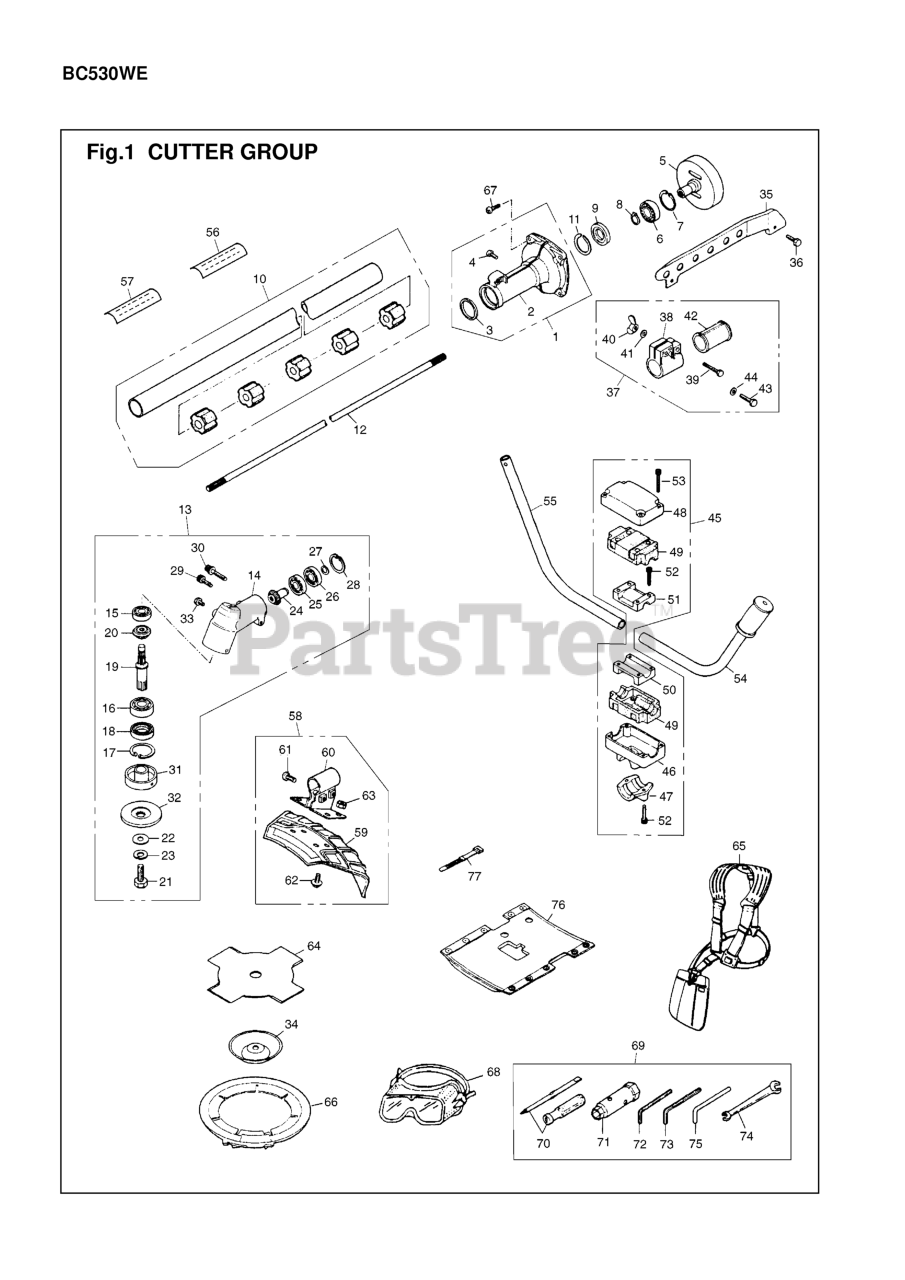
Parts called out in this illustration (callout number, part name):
1	HOUSING (RPLS -11101)
5	DRUM, SPLINED
6	BEARING
7	RING, SNAP, M35 X 1.5
8	RING, SNAP, M15 X 1.0
10	PIPE COMP
12	SHAFT (USE 6340-12211)
13	GEARCASE ASSY
14	GEARCASE
15	BEARING
17	RING, SNAP, M35 X 1.5
19	SHAFT (RPLS -13211)
21	BOLT (REPLACES 3130-13260)
22	WASHER, M10 x 3.2
23	WASHER
25	BEARING
26	BEARING
28	RING
29	BOLT
30	BOLT
31	HOLDER (A) (RPLS -13240)
32	HOLDER (B)
34	COVER
40	NUT (RPLS 01540-20632)
41	WASHER, M6 x .8
44	WASHER, M6 x .8
46	BRACKET (RPLS -14111)
49	ABSORBER
51	CLAMP (B)
52	BOLT, M5 X 25
53	BOLT, M5 X 30
54	HANDLE L
56	PLATE, NAME
57	PLATE, CAUTION
58	GUARD ASSY
59	GUARD
64	SAW BLADE
65	HARNESS ASSEMBLY
66	COVER (REPLACES D0041) ACC.
67	BOLT, M6 x 20
70	DRIVER
73	WRENCH (TOOL)
74	SPANNER
75	BAR
76	PROTECTOR (RPLS-17111)
77	BAND
